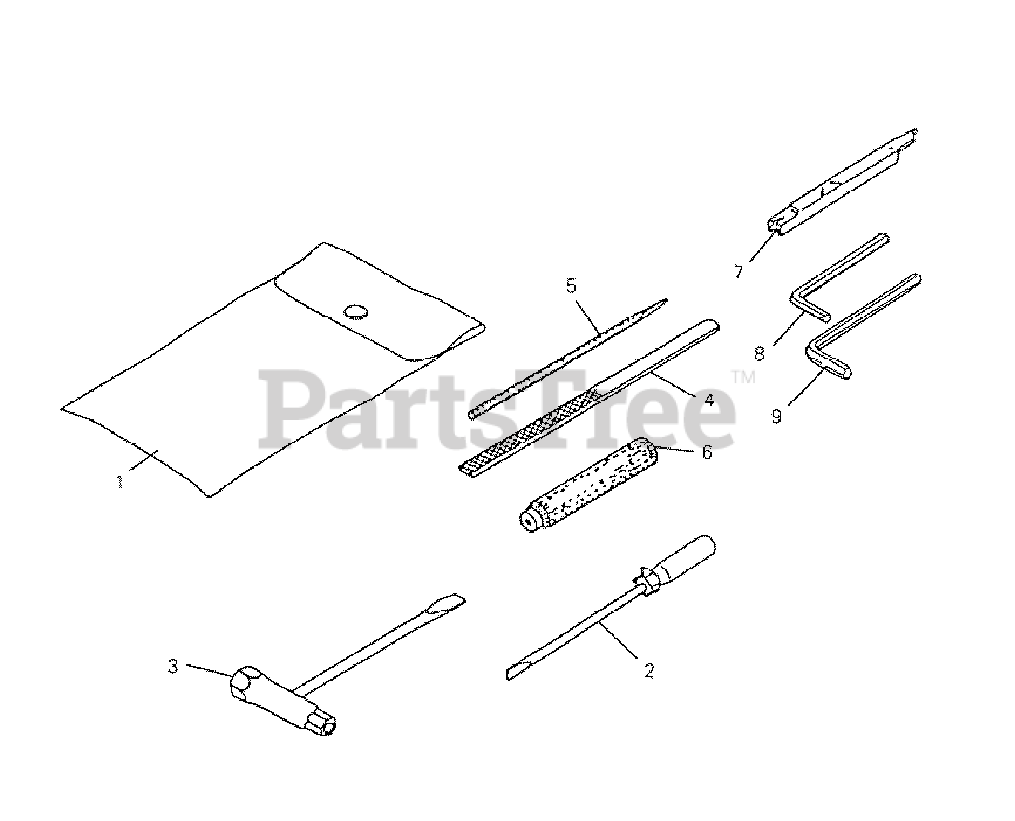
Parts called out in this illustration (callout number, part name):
1	BAG, TOOL
2	SCREWDRIVER
3	T-WRENCH
4	FILE
5	FILE
6	GRIP
7	GAUGE
8	HEX KEY - 3mm
9	HEX KEY - 4mm
